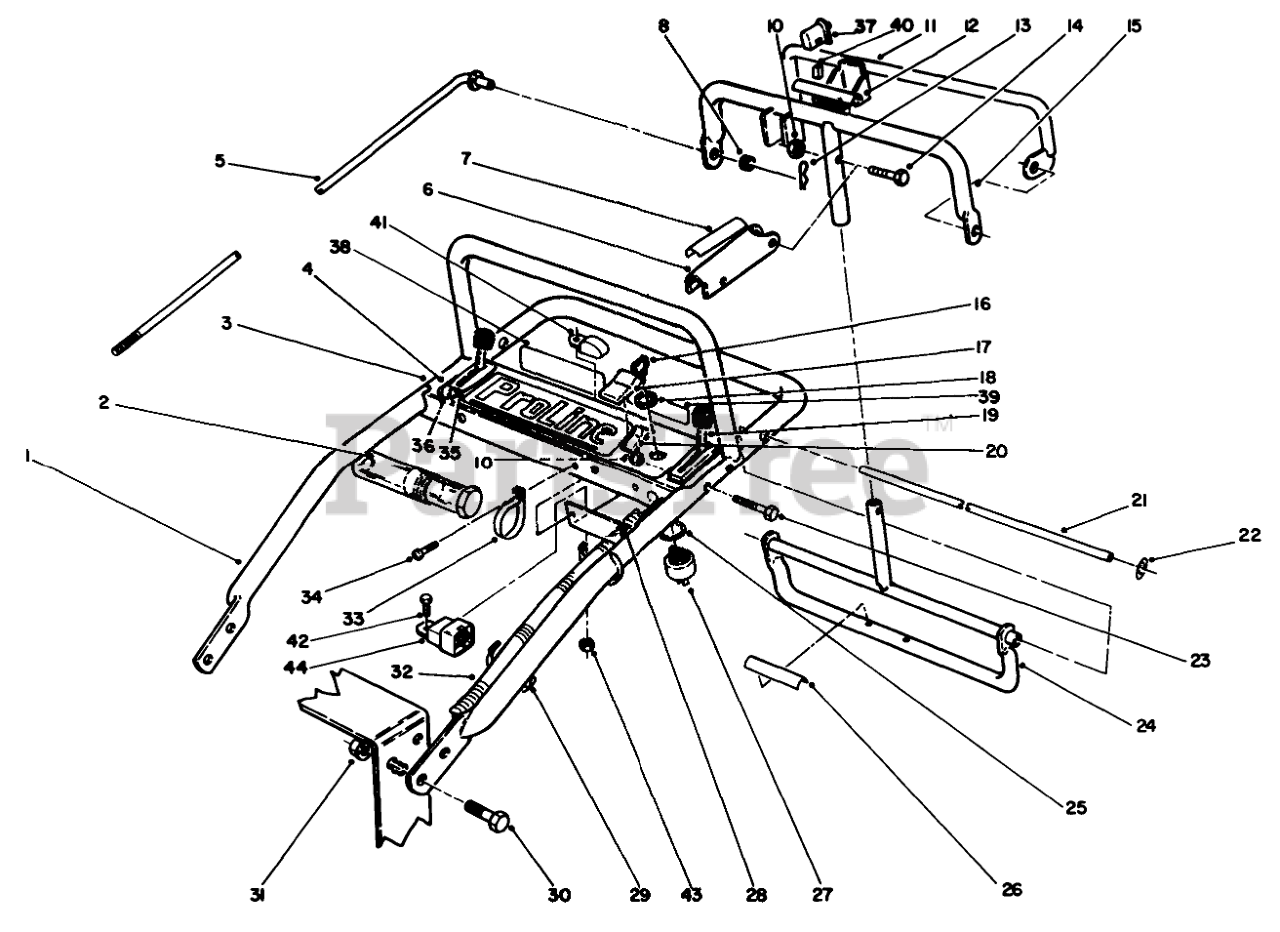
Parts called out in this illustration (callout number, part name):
1	Handle-Upper
2	TUBE-MANUAL
3	Panel-Control
4	DECAL-CNTRL PANEL-30175
5	ROD-CONTROL
6	Lever-Parking Brake
7	DECAL-LEVER, PARKING
8	GROMMET-RUBBER
10	NUT-LOCK, NI
11	SWITCH-BAIL
12	DECAL
13	PIN-COTTER
14	SCREW-SHH
15	Bar
16	KEY-IGNITION
17	BOOT-SWITCH
18	NUT-HH
19	THROTTLE CONTROL
20	Switch-Clutch (Incl. Ref. #17)
21	PIVOT ROD
22	NUT-PUSH-ON, CIRCULAR
23	SCREW-SHH
24	Control Pivot
25	WASHER-TOOTH, INTERNAL
26	DECAL
27	Switch-Ignition (Incl. Ref. #16, 18, & 25)
28	Panel-Bottom
29	TIE-CABLE
30	SCREW-HHF
31	NUT-HF
32	Wire Harness (Ref.)
33	CLAMP-R
34	SCREW-HWHTF
35	CHOKE CONTROL
36	SPACER
37	Bail
38	DECAL-INSTRUCTION, SAFETY
39	DECAL-INSTRUCTION
40	CONNECTOR-BODY
41	Module
42	SCREW-HH
43	NUT-LOCK, NI
44	RELAY
